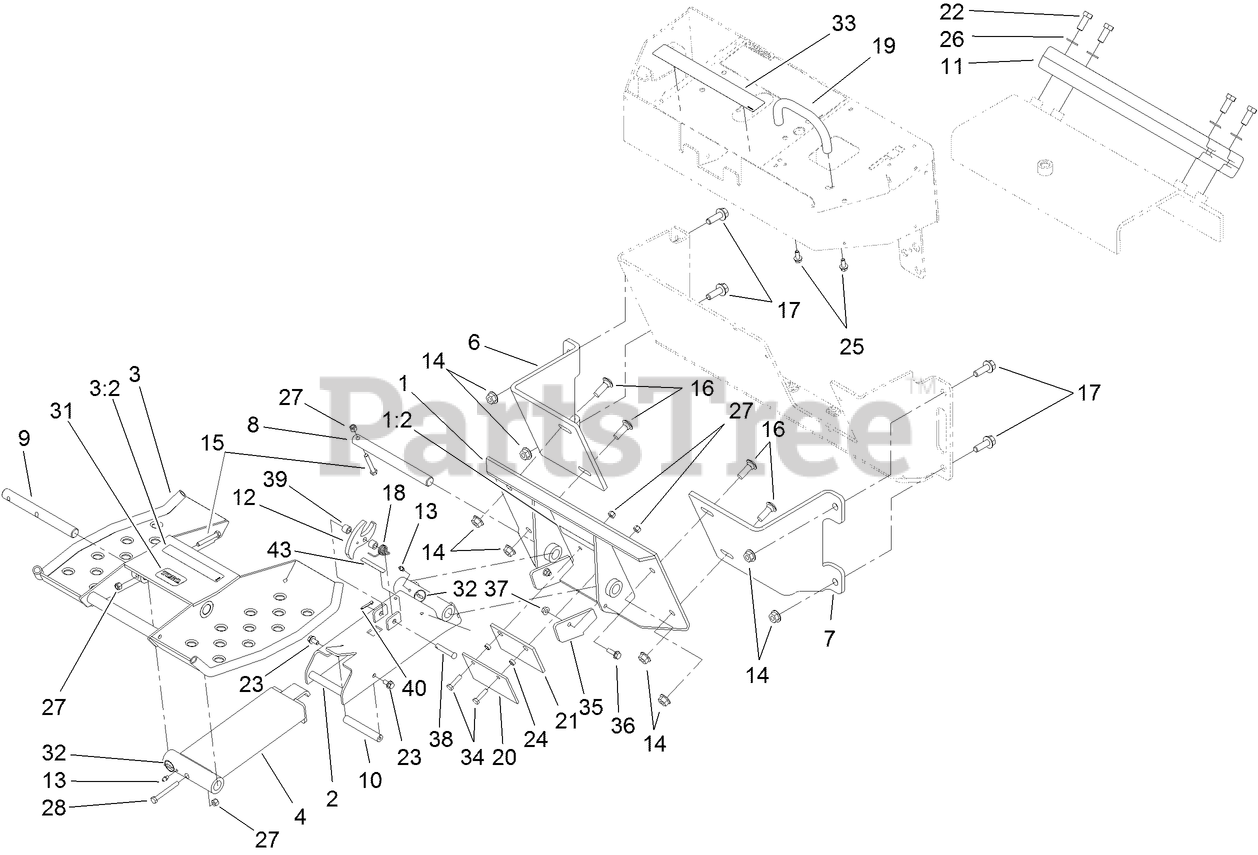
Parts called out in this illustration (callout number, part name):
1	SULKY MOUNTING PLATE ASM
1:2	DECAL-POINT, PINCH
2	LINKAGE ASM
3	PLATFORM ASM
3:2	DECAL-POINT, PINCH
4	SLIDE ASM, WELDED
6	MOUNT-DIESEL, LH
7	MOUNT-DIESEL, RH
8	PIN-UPPER
9	PIN-LOWER V
10	ROD-CLAMP
11	COUNTERWEIGHT-FRONT
12	LATCH-PLATFORM
13	FITTING-GREASE
14	NUT-HHF
15	SCREW-HH
16	SCREW-HH
17	SCREW-HHF
18	SPRING-TORSION, RH
19	BAR-REFERENCE
20	PLATE-PUSH
21	PAD-RUBBER
22	SCREW-HH
23	SCREW-HHF
24	SPACER
25	SCREW-HH
26	WASHER-FLAT
27	NUT-LOCK, NI
28	SCREW-HH
31	DECAL
32	DECAL-GREASE
33	DECAL-WARNING/INSTRUCTIONAL
34	SCREW-HH
35	PLATE-BUMPER
36	SCREW-HHF
37	NUT-HF
38	PIN-CLEVIS
39	SPACER
40	PIN-COTTER
43	DECAL-WARNING
